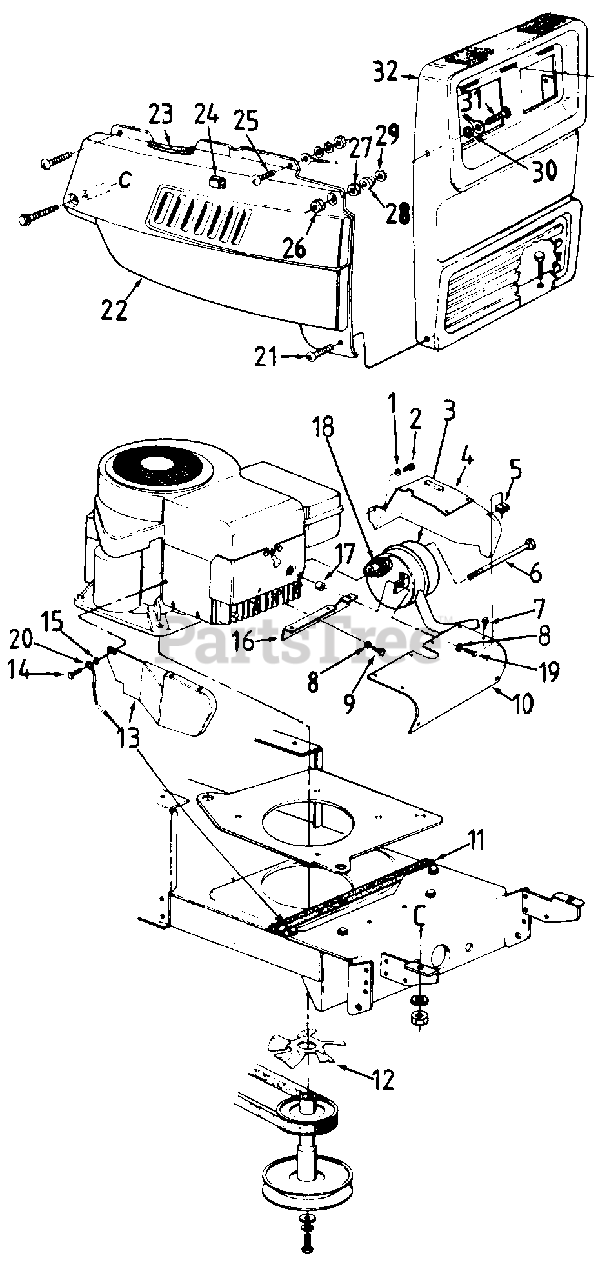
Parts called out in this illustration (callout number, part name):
1	L-Wash. 1/4" I.D.
2	Hex Tap Scr. 1/4-20 x .5"
3	Muffler
4	Muffler Heat Shield-L.H.
5	U-Type Speed Nut #10-24 Thd.
6	Shoulder Bolt
7	Hex AB-Tap Scr. #10 x .5"
8	Spr. Wash. 1/4" I.D.
9	Hex Bolt 1/4-20 x .62" Lg.
10	Muffler Heat Shield-Front
11	Foam Strip
13	Muffler Heat Shield-R.H.
14	Truss Mach. Scr. 5/16-18 x .75" Lg.
15	L-Wash. 5/16" I.D.
16	Heat Shield Bracket
17	Spacer
18	Exhaust Gasket
19	Hex Bolt 1/4-20 x 1" Lg.
20	Ground Wire
21	Truss Mach. Scr. 1/4-20 x .5" Lg.
22	Side Cover-R.H.-B&S
23	Trim Strip-6"
24	Clamp
25	Truss Mach. Scr. 1/4-20 x .75" Lg.
26	Acorn Nut 1/4-20 Thd.
27	Hex Nut 1/4-20 Thd.
28	Shld. Spacer
29	Washer.39" I.D.
30	Ext. L-Wash. 1/4" I.D.
31	Hex Bolt 1/4-20 x .88" Lg.
32	Grille-Used w/Headlight Bezel
